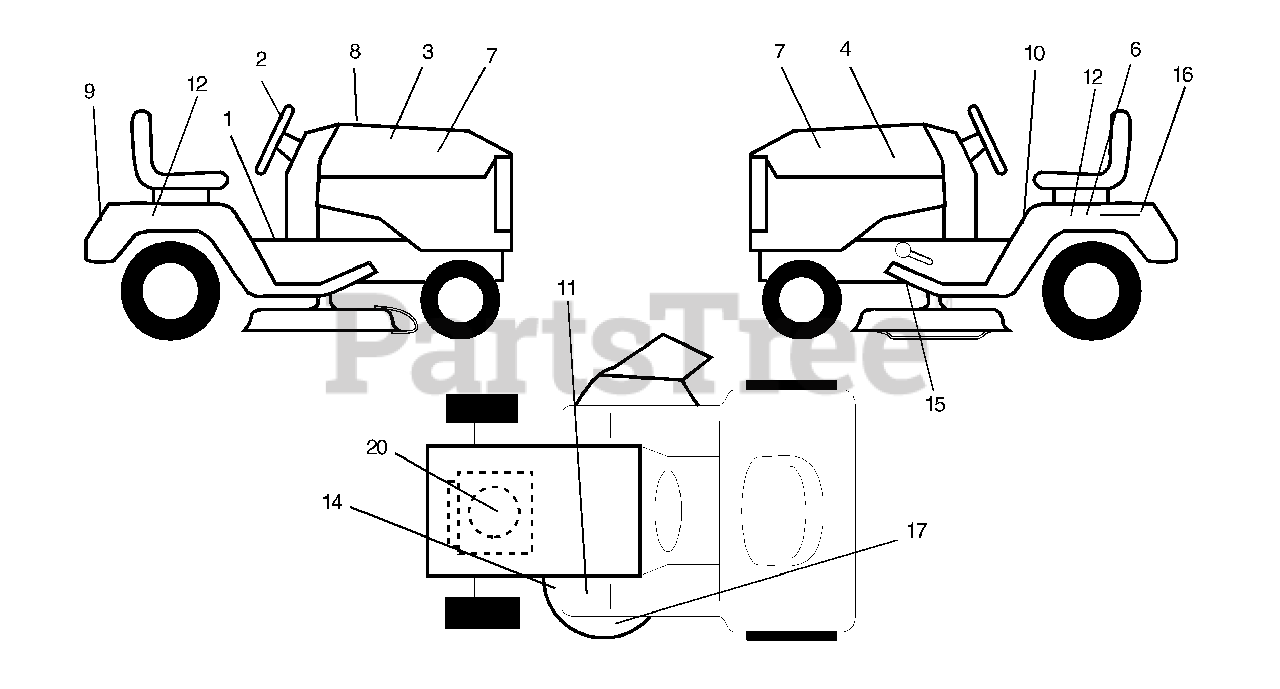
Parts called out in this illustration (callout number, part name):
1	Decal Instruction Operat English
2	Decal Ins Strg Wh
3	Decal Hood Rh
4	Decal Hood Lh
6	Decal, Battery Power Pro
7	Decal Panel Side
8	Decal Replacement Parts
9	Decal Fender Logo
10	Decal Danger English
11	Decal Clutch/brake English
12	Decal Fender
14	Decal V-belt Schematic 42"
15	Decal Schematic
16	Decal Battery Danger/Poison
17	Decal Deck Enviro
20	Decal HP Engine
